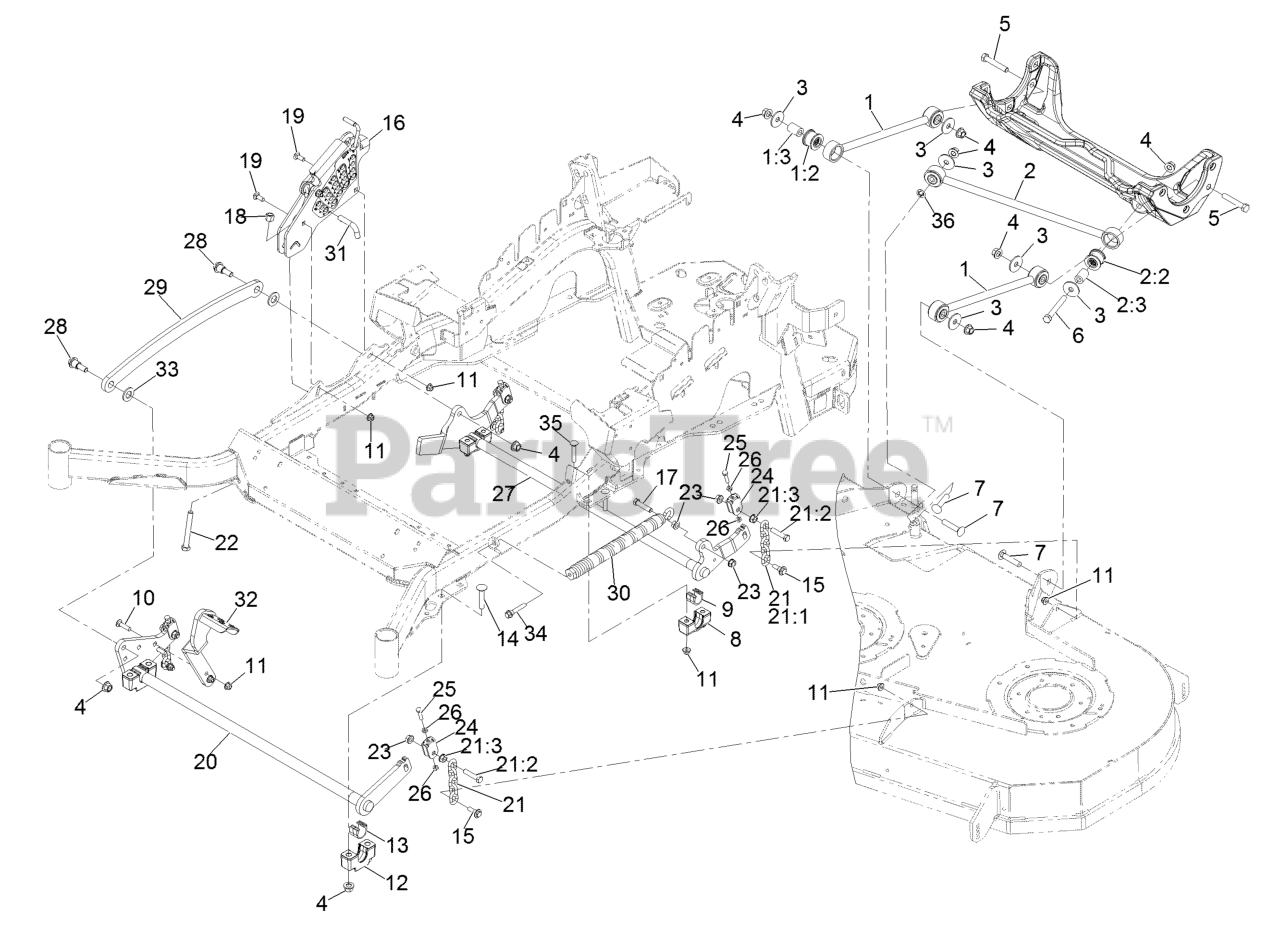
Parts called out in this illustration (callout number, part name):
1	Deck Strut ASM
1:2	Bushing-Suspension, Rubber
2	Panhard Rod ASM
2:2	Bushing-Suspension, Rubber
4	Nut-Lock 1/2-13
5	Screw-HH 1/2-13 X 3
6	Screw-HH 1/2-13 X 4
7	Bolt-Carriage 1/2-13 X 2 1/2
8	Support-Cross Shaft, Bearing Rear
9	Bearing-Cross Shaft, Rear
10	Bolt-Carriage 3/8-16 X 1 1/2
11	Nut-Nyloc 3/8-16 Flg
12	Support-Cross Shaft, Bearing
13	Bearing-Cross Shaft, Front
14	Bolt-Carriage 1/2-13 X 2 1/2 Spl Neck
15	Screw-Hex Flange 3/8-16 X .80
16	HOC ASM
17	Screw-HH 7/16-14 X 2
18	Nut-Nyloc 1/2-13
19	Bolt-Carriage 3/8-16 X 1
20	Decklift-Front
21	Deck Lift Chain ASM
21:1	Chain-Lift, Deck
21:2	Screw-HH 7/16-14 X 2
21:3	Nut-Whizlock 7/16-14
22	Bolt-HH 1/2-13 X 4 Tap
23	Nut-Whizlock 7/16-14
24	Yoke-Adjust, Deck
25	Screw-HH 5/16-18 X 1 1/4
26	Nut-Jam 5/16-18
27	Lift-Deck, Rear
28	Screw-Shoulder HHF 1/2-13 X 1.12
29	Link-Lift, Deck
30	Spring-Extension
31	Pin-HOC
32	Lever-Foot
33	Washer-3/4 SAE
34	Screw-Shcs 3/8-16 X 2.212
35	Bolt-Carriage 3/8-16 X 2 1/4
36	Nut-Push
